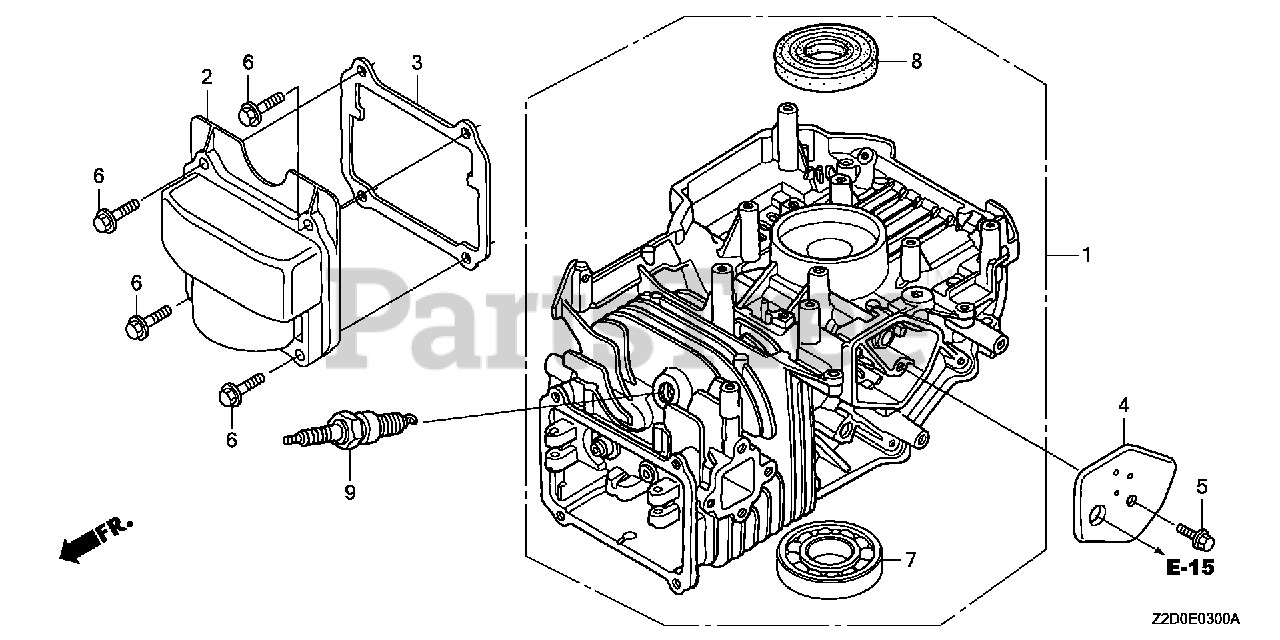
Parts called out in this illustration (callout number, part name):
1	CYLINDER ASSY.
2	COVER, CYLINDER HEAD
3	GASKET, HEAD COVER
4	COVER, BREATHER (BREATHER VALVE ASSY.)
5	BOLT, FLANGE (6X14) (CT200)
6	BOLT, FLANGE (6X25) (CT200)
7	BEARING, RADIAL BALL
8	OIL SEAL (25.4X74X6)
9	SPARK PLUG (BPR6ES) (NGK)
